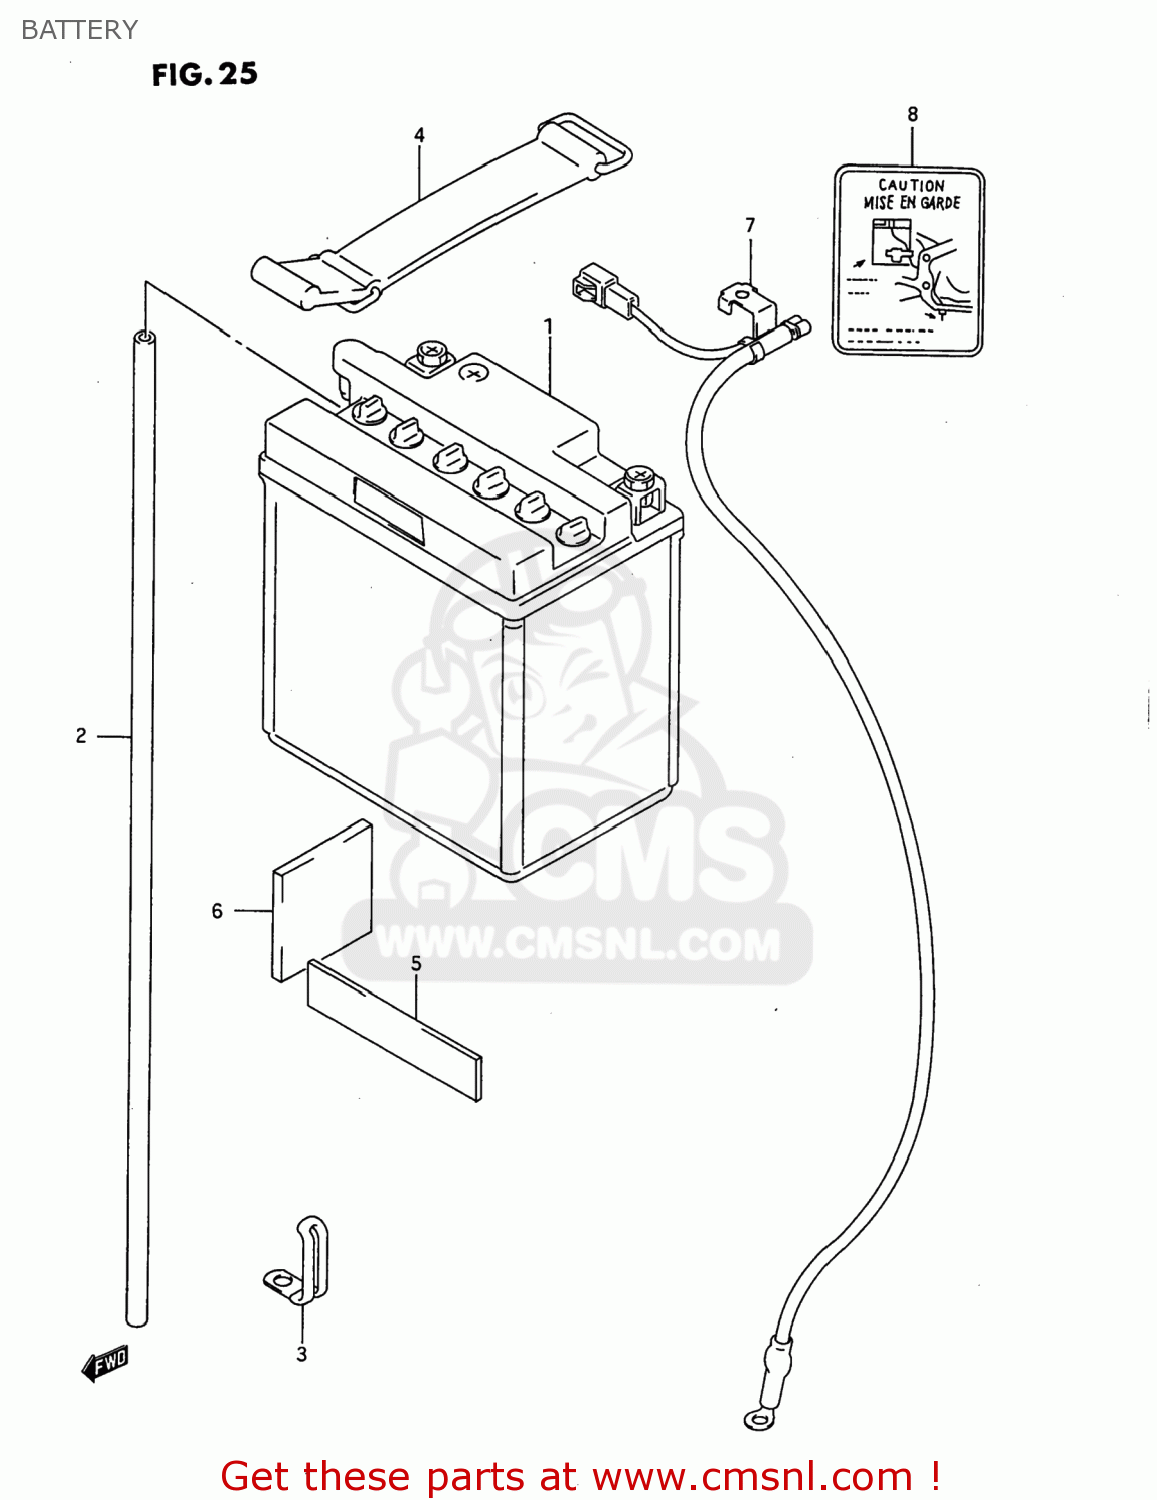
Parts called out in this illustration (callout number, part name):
1	BATTERY ASSEMBLY (12V)
2	HOSE,BATTERY EXHAUST(L:780)
3	CLAMP(L:45)
4	BAND
5	PROTECTOR(170X95X3.0)
6	PROTECTOR(50X50X5)
7	WIRE,BATTERY MINUS LEAD
8	PLATE,BATTERY CAUTION
